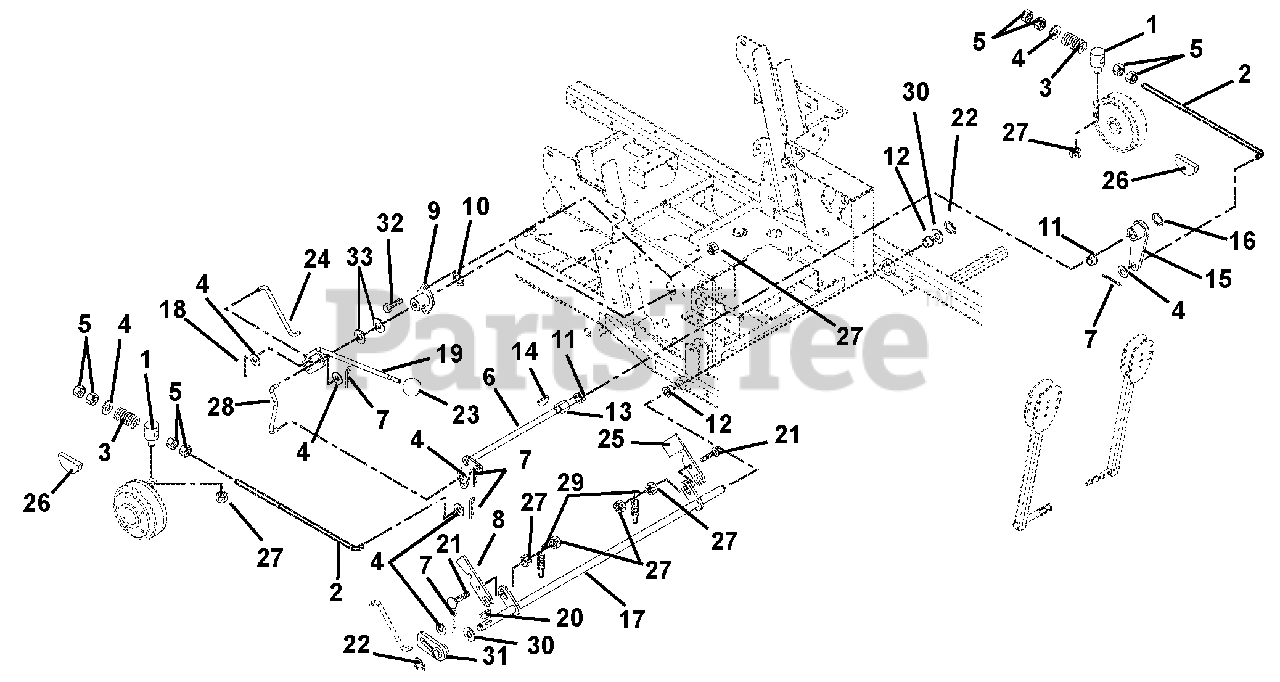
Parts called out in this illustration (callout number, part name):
1	Pivot, Brake Rod
2	Rod, Brake .38 x 19.00
3	Spring, Compression .143 x .71 x 2.00
4	Washer, Flat Steel .406 x .812 x .065
5	Nut, Hex .38-16
6	Shaft, Brake Cross
7	Pin, Hair
8	Slide, Interlocking Brake
9	Bushing, Flange
10	Ring, Retaining External .625 x .05
11	Bushing, Flange Nylon .762 x 1.00 x .58 x 1.48
12	Bushing, Flange .515 x .75 x .745 x 1.00
13	Bushing, Sleeve .75 x 1.00 x .75
14	Key, Woodruff .19 x .75 Hard #9
15	Arm, Brake Left Hand
16	Ring, Retaining External .625 x .050
17	Weldment, Mechanical Brake
18	Pin, Cotter External .09 x .75
19	Weldment, Brake Actuating
20	Key, Woodruff .13 x .63
21	Bolt, Round Head Square Neck .31-18 x 1.25 Grade 5
22	Ring, Retaining External .50 x .05
23	Knob, Steering Lock
24	Linkage, Brake Actuating
25	Interlock, Safety Switch
26	Pad, Disk Brake
27	Nut, Locking, Top Flange .31-18
28	Linkage, Brake Actuating
29	Spring, Tension .063 x .44 x 1.56
30	Washer, Flat Steel .505 x 1.00 x .062
31	Weldment, Parking Brake Hub
32	Bolt, Hex .31-18 x .75 Grade 5
33	Washer, Flat Steel .630 x 1.250 x .062
